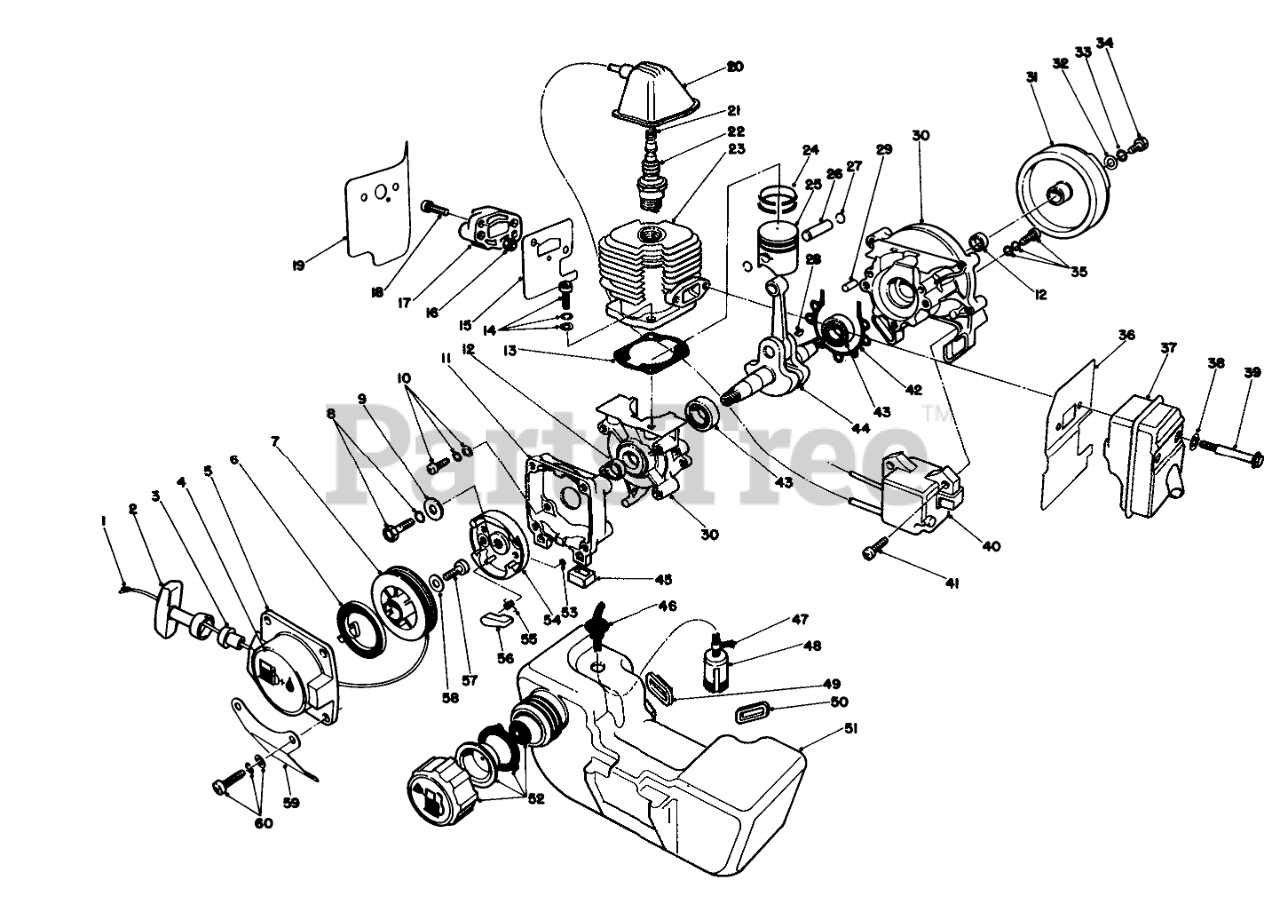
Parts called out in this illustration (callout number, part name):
1	STARTER ROPE
2	STARTER KNOB
3	ROPE GUIDE
4	DECAL - FUEL MIX
5	Case-Reel (Incl. Ref. #4)
6	SPIRAL SPRING
8	BOLT ASSEMBLY
9	WASHER
10	SCREW ASSEMBLY
11	Case-Pulley
12	OIL SEAL
13	CYLINDER PACKING
15	INSULATOR PACKING
16	INSULATOR NUT
17	Insulator Assembly (Incl. Ref. #16)
18	SCREW
19	GASKET
20	PLUG CAP
21	PLUG CAP SPRING
22	SPARK PLUG
23	CYLINDER
24	PISTON RING
25	PISTON
26	PISTON PIN
28	WOODRUFF KEY
30	Crankcase Assembly (Incl. Ref. #12, 29 & 41-44)
31	FLYWHEEL
32	WASHER
33	SPRING WASHER
35	SCREW ASSEMBLY
36	MUFFLER GASKET
37	MUFFLER ASSEMBLY
38	WASHER
39	MUFFLER CLAMPING BOLT
40	IGNITION COIL
41	SCREW
42	CRANKCASE PACKING
43	BALL BEARING
44	CRANKSHAFT
45	RUBBER CUSHION
46	RUBBER TUBE
47	HOSE CLAMP
48	FILTER
49	RUBBER PLATE
50	RUBBER PLATE
51	Tank-Fuel
52	GAS CAP
53	E RING
54	STARTER PULLEY
55	RETURN SPRING
56	RATCHET
57	SETSCREW
58	WASHER
59	TANK STAY
60	SCREW ASSEMBLY
